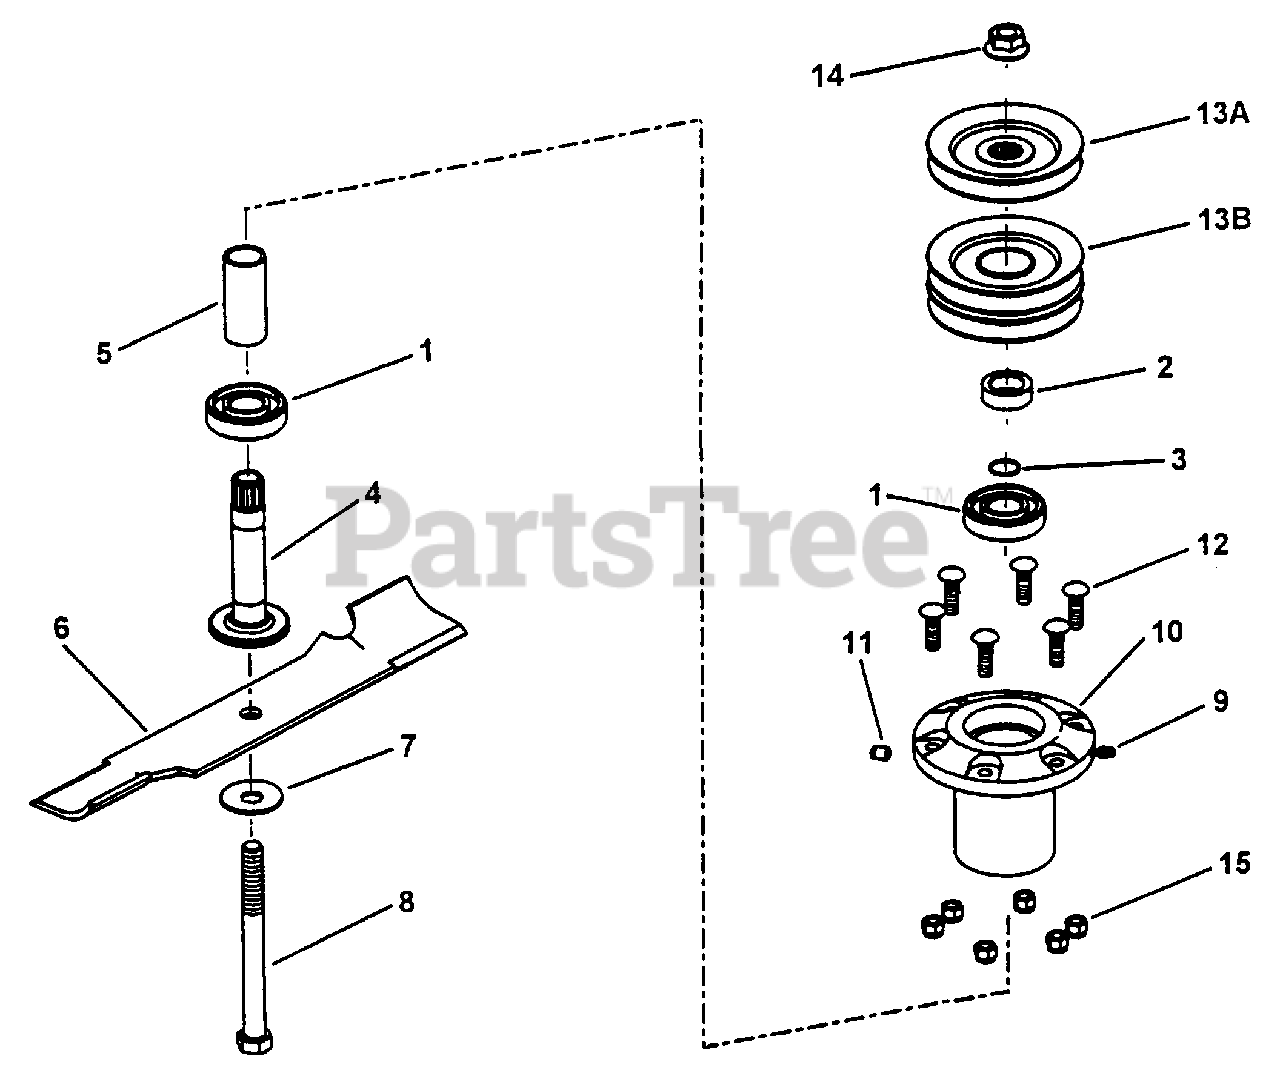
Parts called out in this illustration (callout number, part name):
1	BEARING, Sealed
2	WASHER, Spindle
3	SNAP-RING, Spindle Shaft
4	SHAFT, Spindle
5	SPACER, Bearing
6	BLADE, 16-1/2" (48" Deck)
7	WASHER, Beveled
8	BOLT, 5/8-18 x 6-5/8" Hex Head, Grade 5
9	LUBE FITTING, 1/4-28 Thread Forming
10	HOUSING, Cutter
10	Spindle Housing Sub-Assembly
11	VENT, Spindle
12	BOLT, 3/8-16 x 1-1/4" Rib Necked
13A	PULLEY, Spindle (48" Deck LH & RH)
13B	PULLEY, Spindle (48" Deck/Drive)
14	NUT, 5/8-18 Hex Flange Lock, Grade 5
15	NUT, 3/8-16 Hex Nyloc
